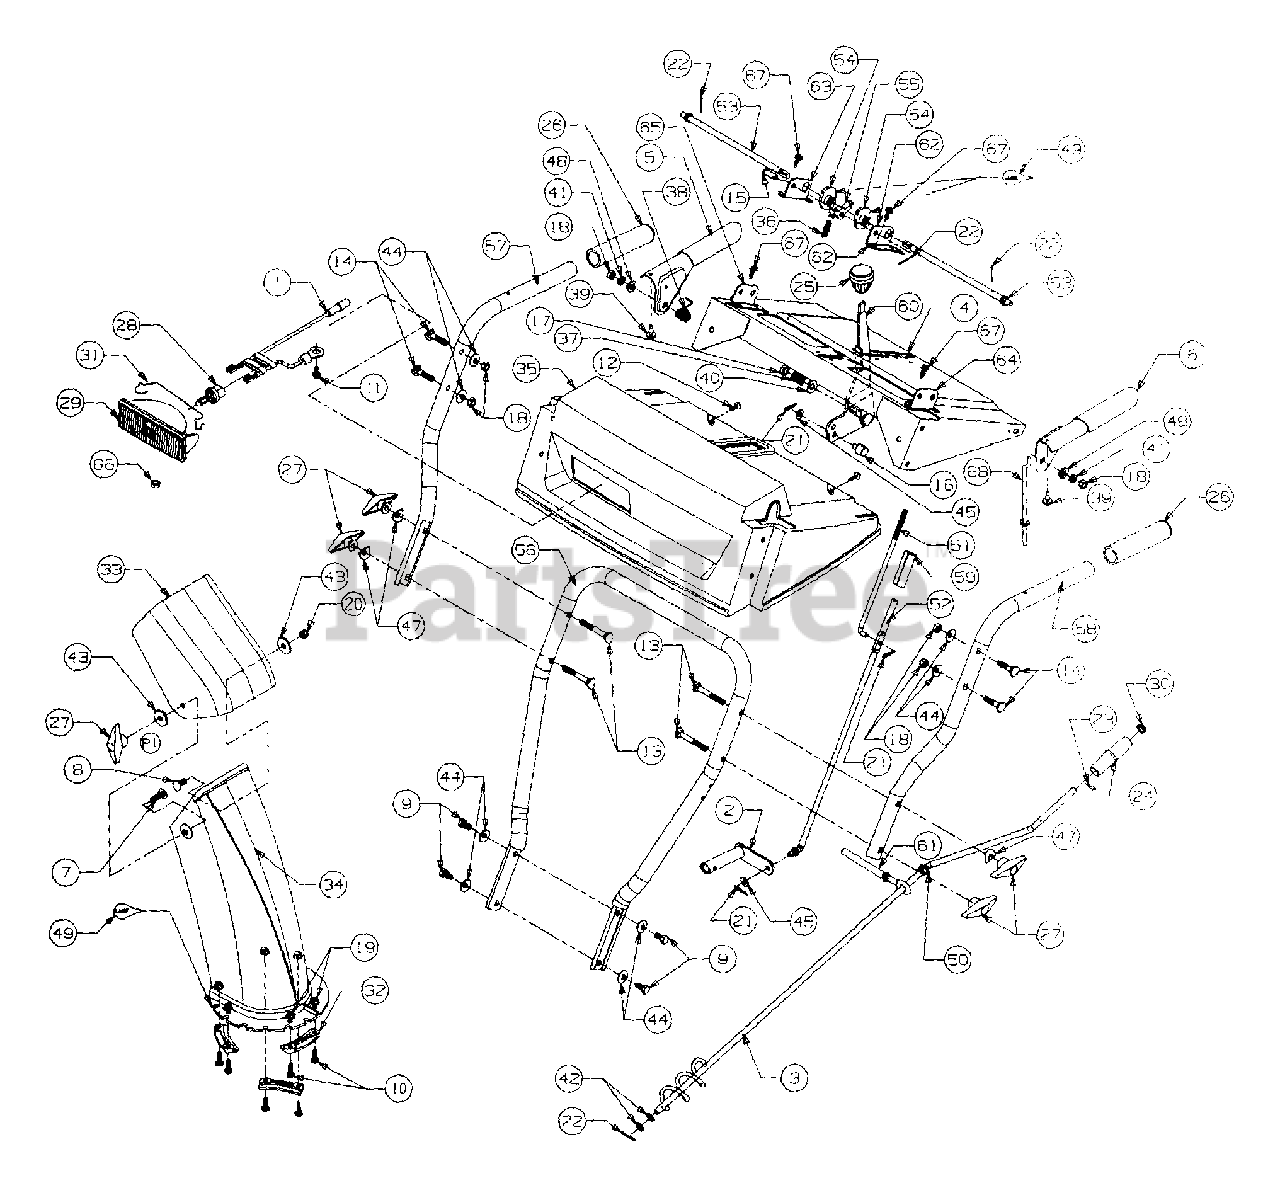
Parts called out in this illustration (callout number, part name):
1	Harness-Snow Thrower
3	Crank-Chute
6	Handle Ass'y. - L.H.
7	Screw-Carriage
8	Screw-Carriage
9	Screw-Hex
10	Screw-Hex
11	Screw-Hex
12	Screw-Hex
13	Bolt-Carriage
14	Bolt-Carriage
15	Pin-Clevis
16	Ferrule
17	Nut-Hex
18	Nut-Hex
19	Nut-Hex Lock
20	Nut-Hex Lock
21	Pin-Cotter
22	Pin-Cotter
23	Pin-Roll
24	Knob-Chute Crank
25	Knob-Shift
27	Knob-Wing Nut
28	Lamp
29	Housing-Lamp
30	Cap-Push
31	Clip-Retaining
32	Keeper-Chute
33	Chute-Upper
34	Chute-Lower
35	Panel-Handle
36	Spring
37	Spring
38	Spring
39	Bumper
40	Washer-Bell
41	Washer-Lock
42	Washer-Flat
43	Washer
44	Washer-Belt
45	Washer-Flat
47	Washer-Saddle
48	Washer
49	Lubricant
50	Bushing-Plastic
51	Rod-Shift Upper
52	Rod-Shift Lower
53	Rod-Cam
54	Cam-Handle Lock
55	Pawl-Handle Lock
59	Connector-Clutch Rod
66	Nut, Sems Hex
67	Screw, Hex Tap
68	Z Fitting
